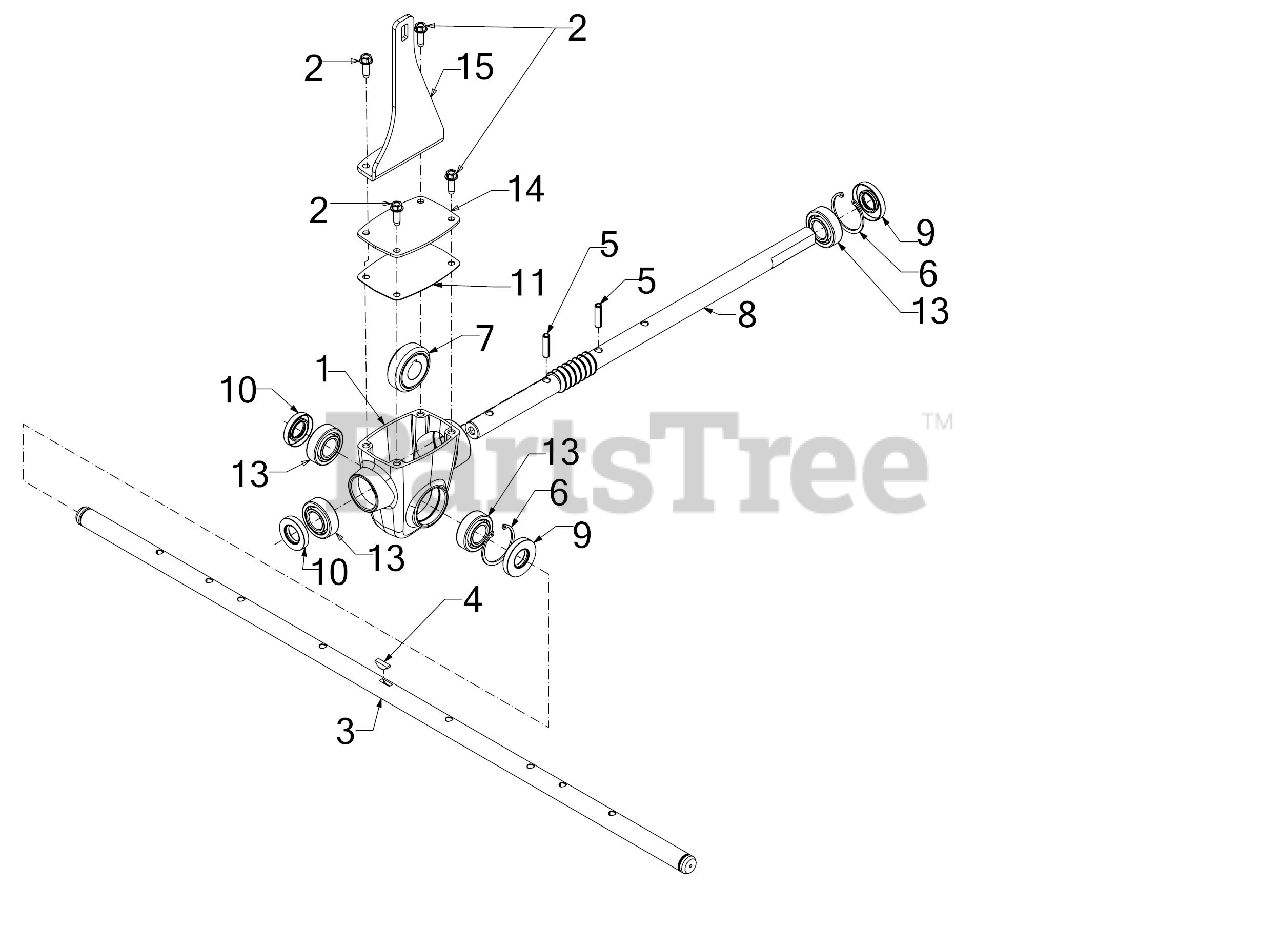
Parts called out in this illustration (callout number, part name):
1	AUGER GEARBOX HOUSING
2	SCREW 1/4-20 x .750
3	34" AUGER AXLE
4	KEY-3/16 x 5/8
7	WORM GEAR 20T
8	WORM SHAFT .75OD
11	GEARBOX COVER GASKET
13	BALL BEARING
14	GEARBOX COVER
15	GEARBOX SUPPORT BRACKET
